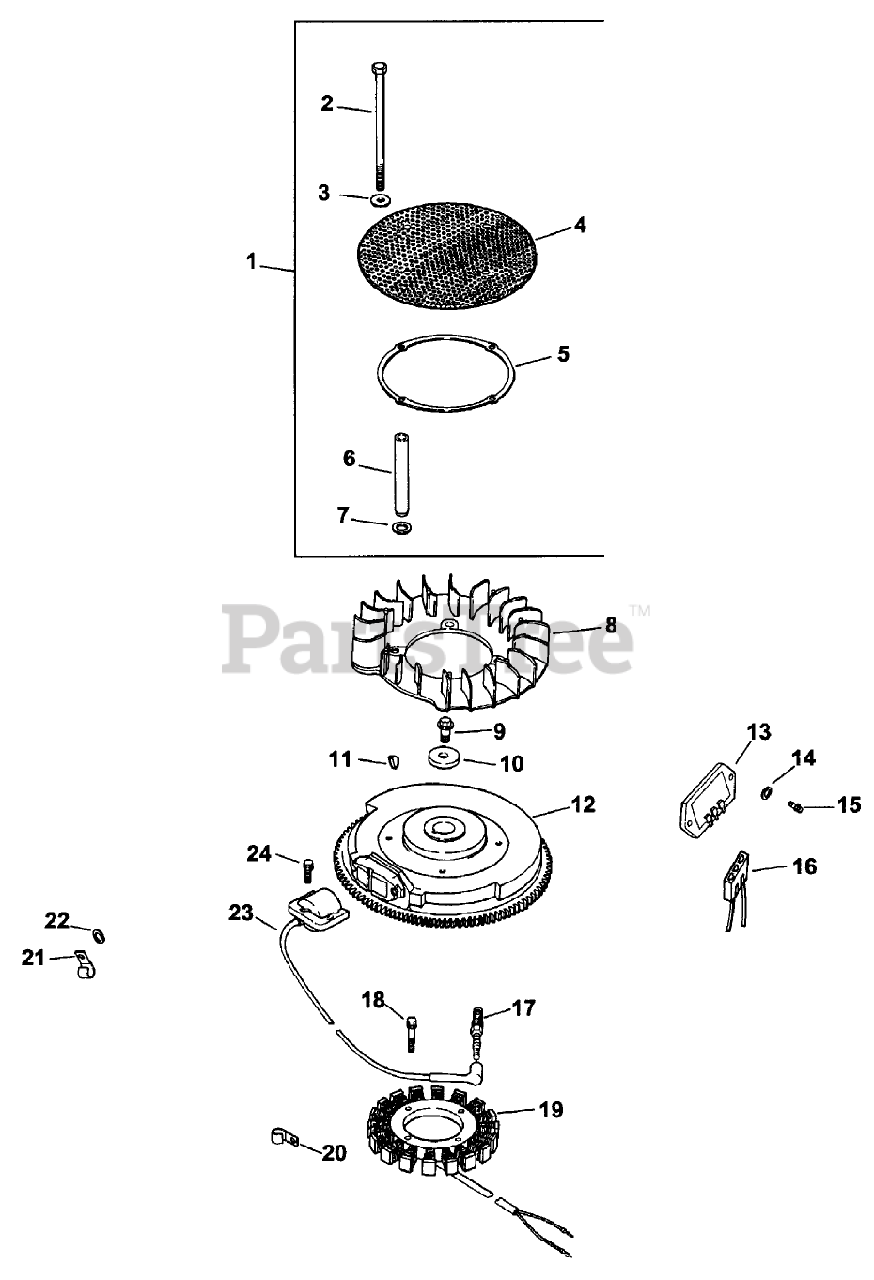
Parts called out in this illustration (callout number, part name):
1	Kit, chopper screen (Includes 2-7)
2	Screw-Hex
3	Washer
4	Screen-Grass
5	Ring-Support
6	Spacer
7	Washer, sping
8	Fan
9	Screw
10	Washer
11	Key
12	Flywheel
13	Rectifier-Regulator
14	Washer
15	Screw
16	Connector
17	Plug-Spark
18	Screw
19	Kit, 15 amp stator (Includes Bracket, stator wire 24 126 71)
20	Clip
21	Clip
22	Washer
23	Module-Ignition
24	Screw
